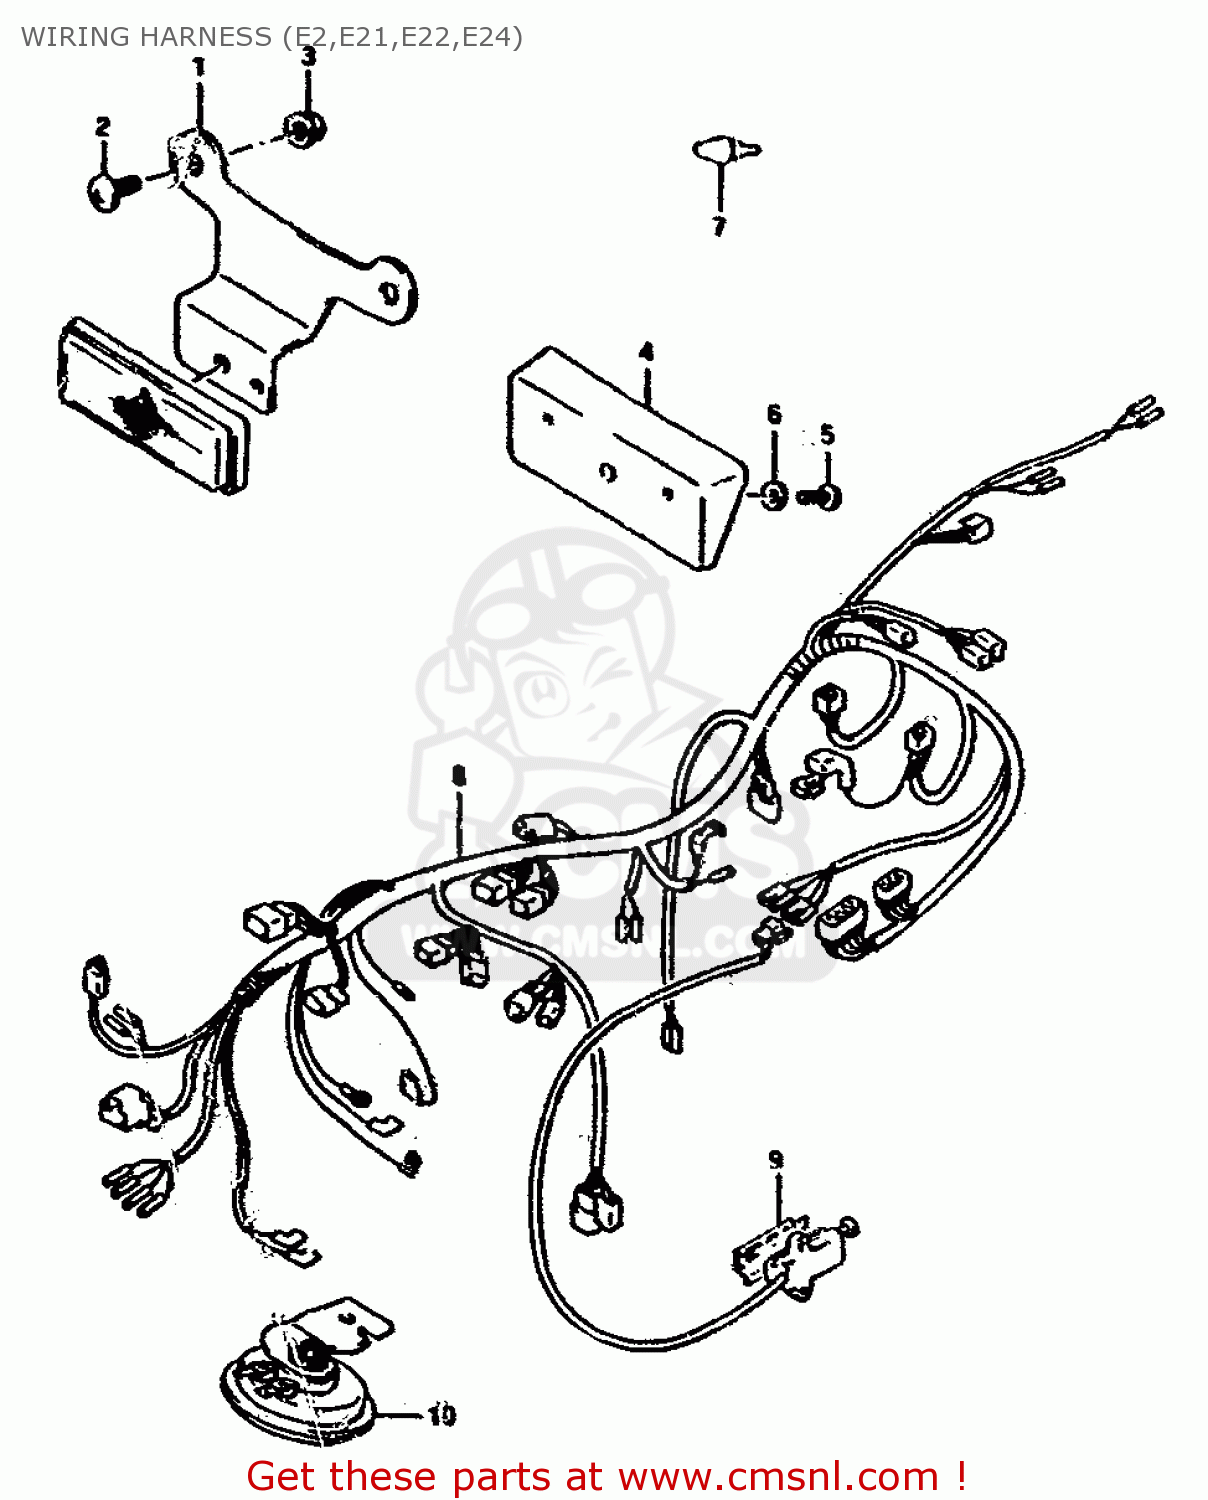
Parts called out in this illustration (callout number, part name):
1	BRACKET,RR RR
2	SCREW 6X12
3	NUT
4	SPACER,RR RR
5	SCREW
6	WASHER
7	CUSHION
8	HARNESS,WIRING
9	SHEET,HEAT PROTECTION
10	HORN ASSY
